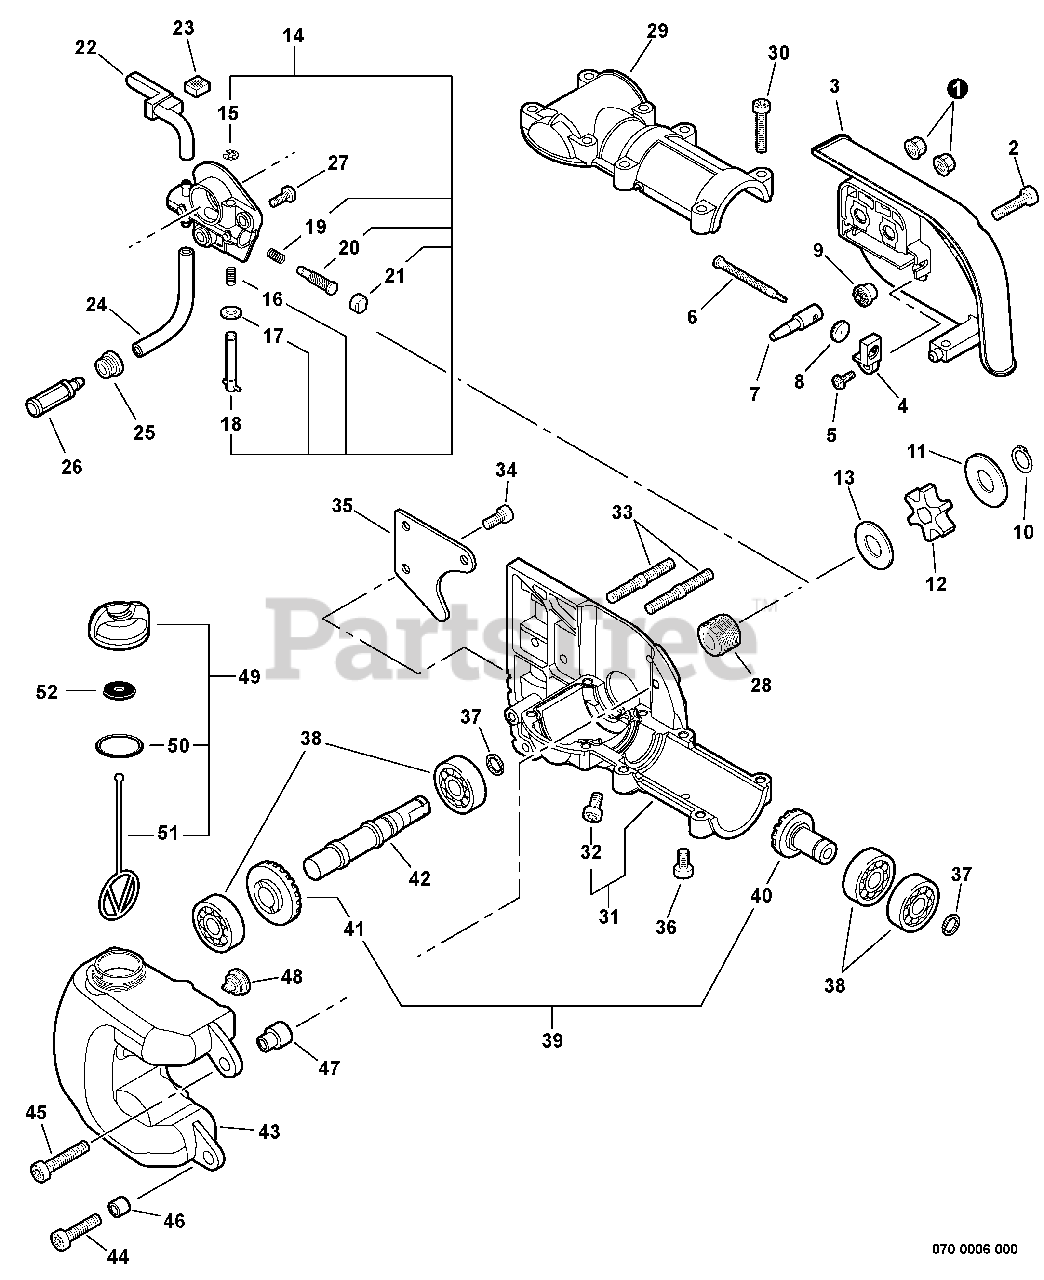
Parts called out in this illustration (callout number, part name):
1	NUT, FLANGE M6
2	BOLT, TORX 5×20
3	GUARD, SPROCKET
4	COLLAR 8
5	SCREW 4
7	TENSIONER, CHAIN
8	GEAR - 14 TOOTH
9	GEAR - 14 TOOTH
10	RING, SNAP
11	WASHER 10
12	SPROCKET, DRIVE
13	WASHER 10.2×24.5×1.2
14	AUTO-OILER ASSY
18	ADJUSTER, OILER
20	PLUNGER ASSY
21	CAP, PLUNGER
22	PIPE, OIL OUTLET
23	PAD, FOAM
24	PIPE, IMPULSE 3×6×75
25	GROMMET
26	FILTER, OIL
27	BOLT, TORX 5×10
28	GEAR, WORM
29	COVER, GEAR CASE
30	BOLT, TORX 5×25
31	CASE, GEAR
32	BOLT, TORX 5×10
33	BOLT, STUD 6
34	SCREW 5×10
36	BOLT, TORX 5×10
37	RING, SNAP Ø12
38	BEARING, BALL
39	GEAR SET
40	GEAR, BEVEL
41	GEAR, BEVEL - 23 TOOTH
42	SHAFT, GEAR
43	TANK, OIL
44	BOLT, TORX 5×20
45	BOLT, TORX 5×25
46	SPACER 6.2×7.8×6
47	COLLAR 6
48	VENT ASSY
49	CAP ASSY
50	O-RING 18
51	CONNECTOR, CAP L= 60 MM
52	GASKET, CAP
